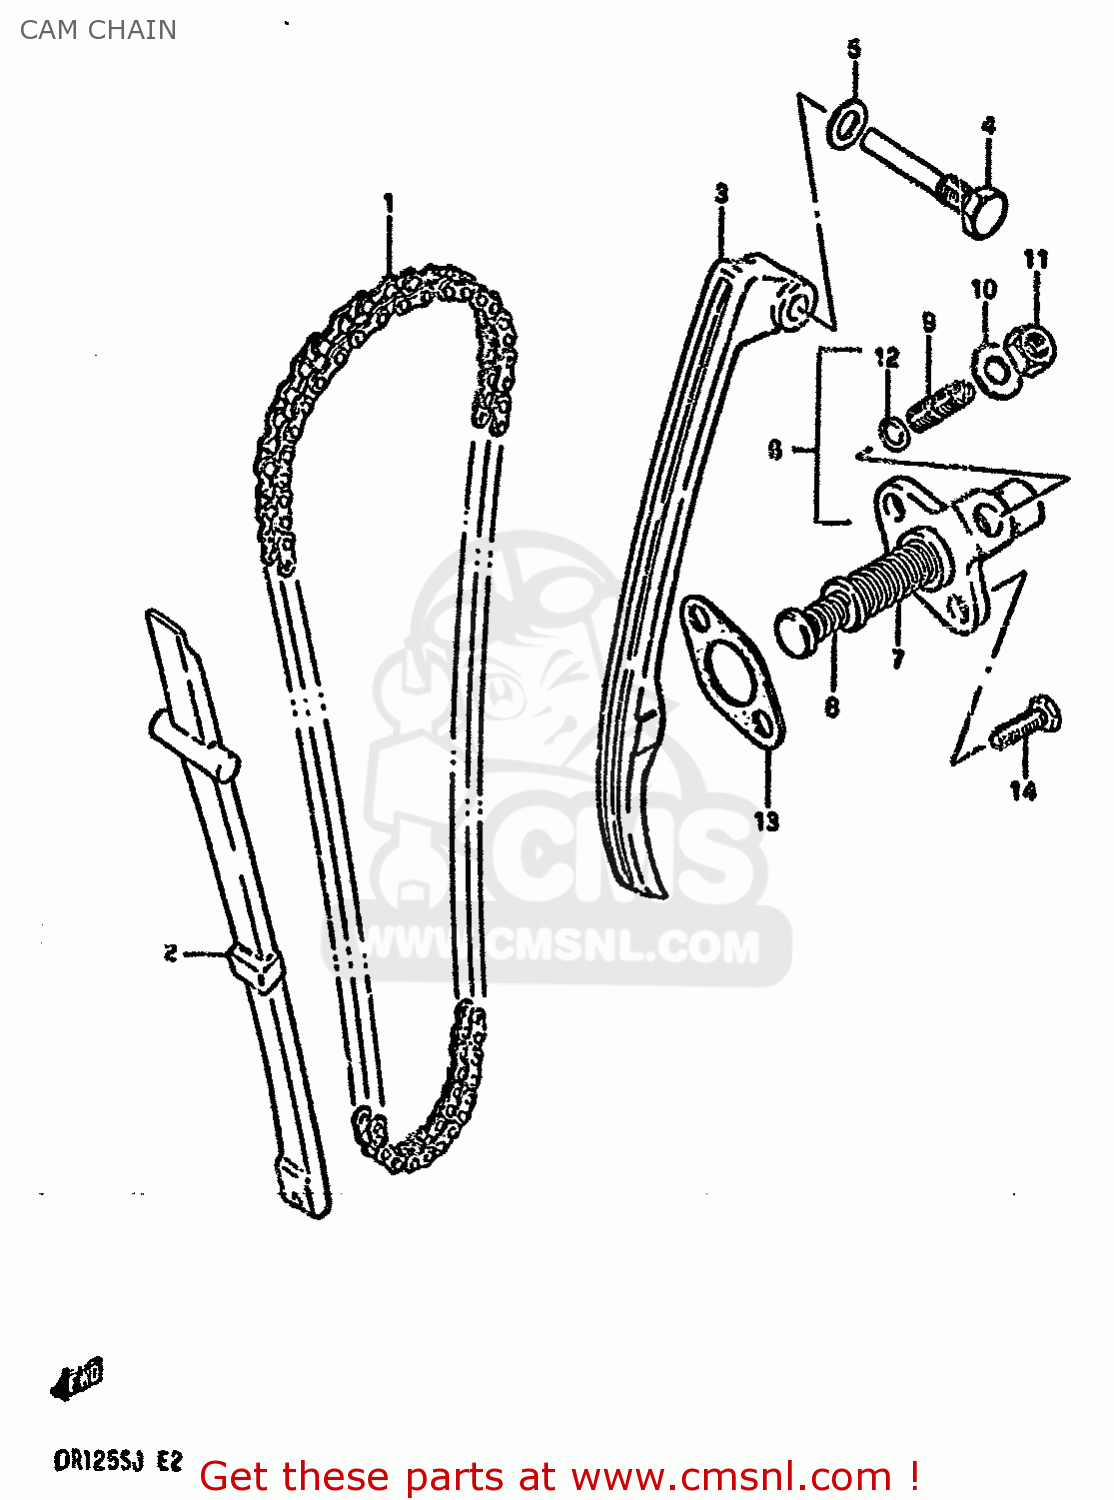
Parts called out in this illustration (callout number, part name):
1	CHAIN,CAMSHAFT DRIVE
2	GUIDE,CAM CHAIN
3	TENSIONER,CAM CHAIN
4	BOLT,CAM CHAIN TENSIONER
5	GASKET 8.2X14X1 (NAS)
6	ADJUSTER ASSEMBLY,TENSIONER
7	SPRING
8	SPRING
9	SCREW
10	WASHER
11	NUT
12	O RING(D:1.9,ID:5.7)
13	GASKET,TENSIONER ADJUSTER (NAS)
14	BOLT
